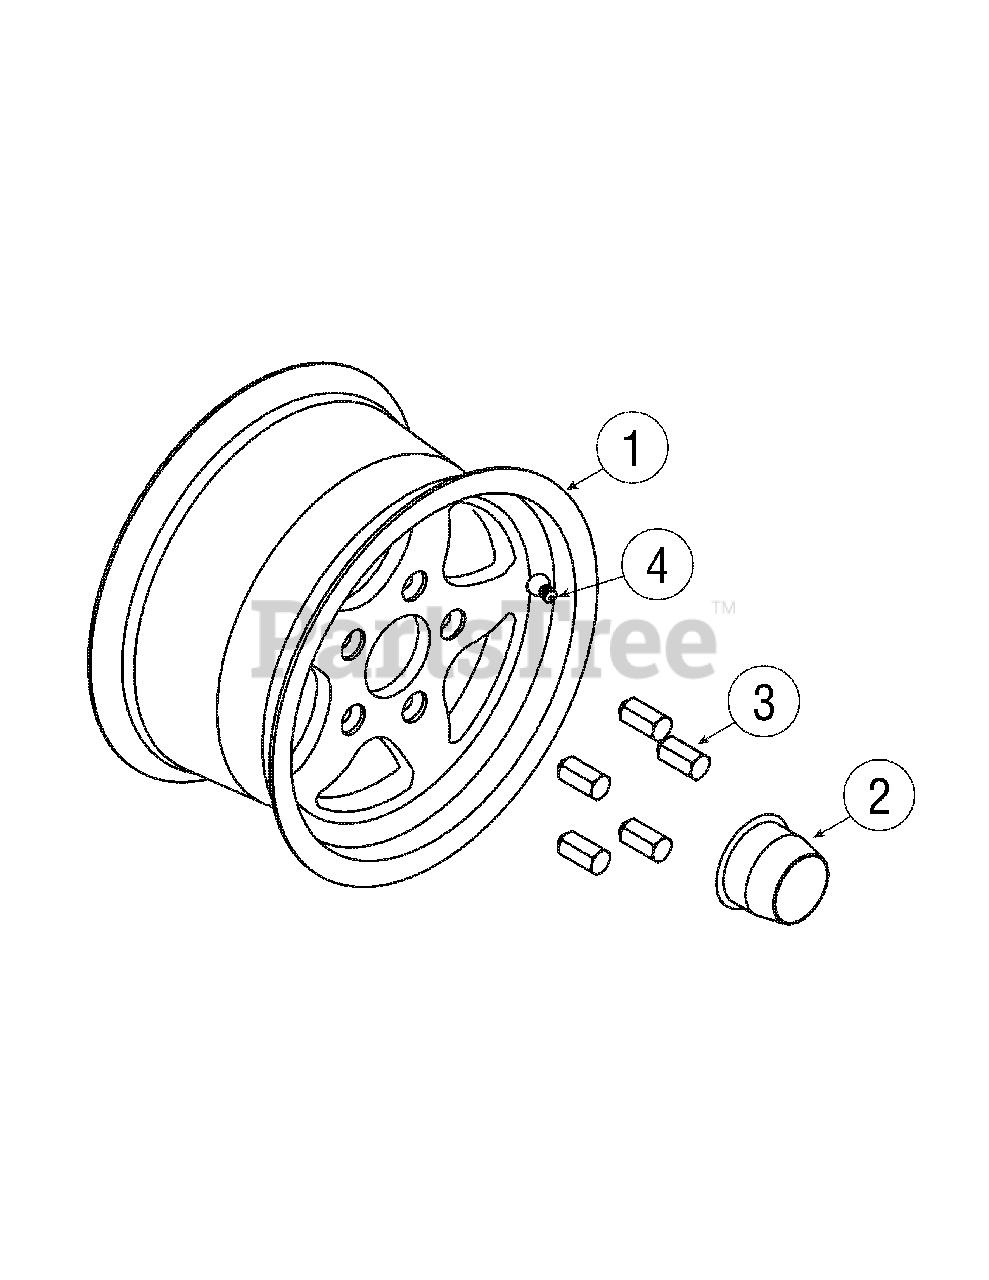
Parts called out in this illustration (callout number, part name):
1	Whl, Assembly, 12 x 7.5, Spoke
2	Cap, Whl, Chrome
3	Nut, Lug, 7/16-14, Chrome
4	Valve, Tubeless, Air
